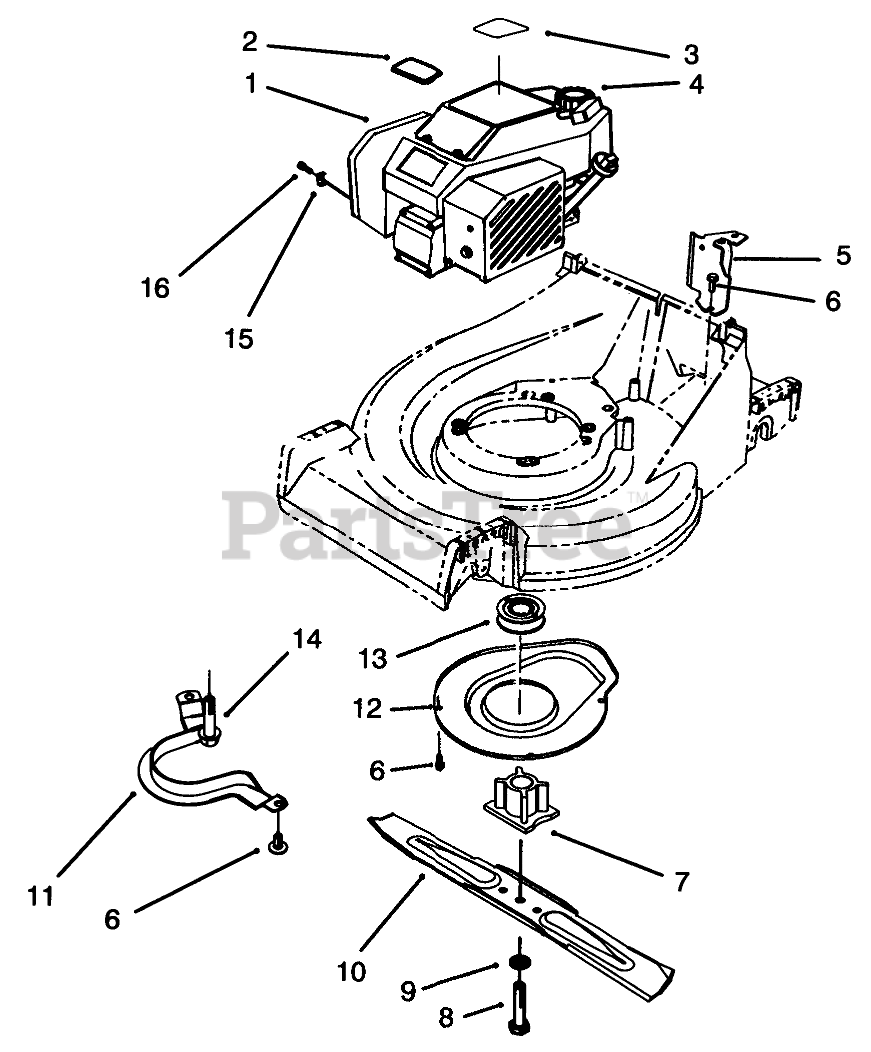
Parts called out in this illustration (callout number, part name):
1	ENG ASM-GTS 150 NC
2	PLATE-LOGO
3	DECAL - ENGINE
4	GAS CAP ASM
5	Bracket-Cable Support
6	SCREW-HWHTF
7	BLADE RETAINER
8	SCREW-BLADE
9	WASHER-LOCK
10	Key
11	Guide-Belt
12	Cover
13	PULLEY-DRIVE, ZONE START
14	SCREW-HWH
15	CLAMP-CASING
16	CLAMP SCREW F/W ENGINE
